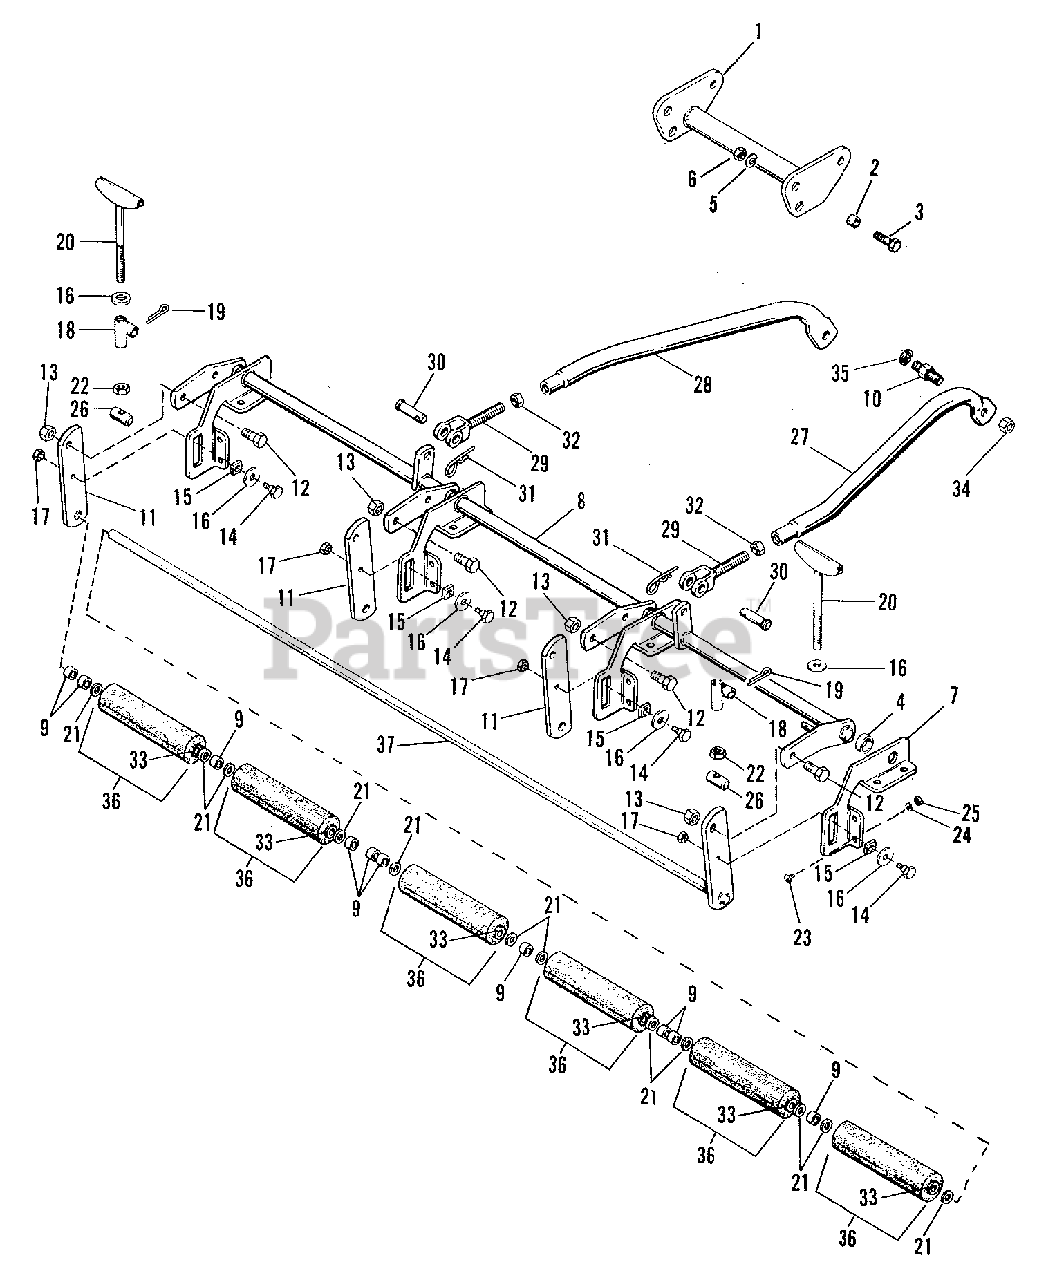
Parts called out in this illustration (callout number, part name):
1	ROCKER ARM ASSEMBLY
3	CAPSCREW, Hex Head, 1/2NC x 1-3/4
5	LOCKWASHER, Spring, 1/2
8	ROCKER ARM ASSEMBLY
10	BOLT, Shoulder, Special
11	BAR, Roller
12	CAPSCREW, Hex Head, 1/2NC x 1-1/4
13	LOCKNUT, Hex, 1/2NC
14	BOLT, Shoulder
16	WASHER, Plain, 1/2
17	LOCKNUT, Hex, Jam, 3/8NC
18	PIVOT ASSEMBLY
19	PIN, Cotter, 3/16 x 1
20	ADJUSTING SCREW ASSEMBLY
22	LOCKNUT, Hex, Full, Jam, 1/2NC
23	CARRIAGE BOLT, 5/16NC x 3/4
24	LOCKWASHER, 5/16
25	NUT, 5/16NC
26	PIN, Clevis
31	CLIP, Hairpin
32	NUT, Hex, Jam, 5/8NC
34	LOCKNUT, Hex, Full, Jam, 5/8NC
35	E-RING, External
36	ROLLER, w/Bushings
37	ROLLER SHAFT ASSEMBLY
